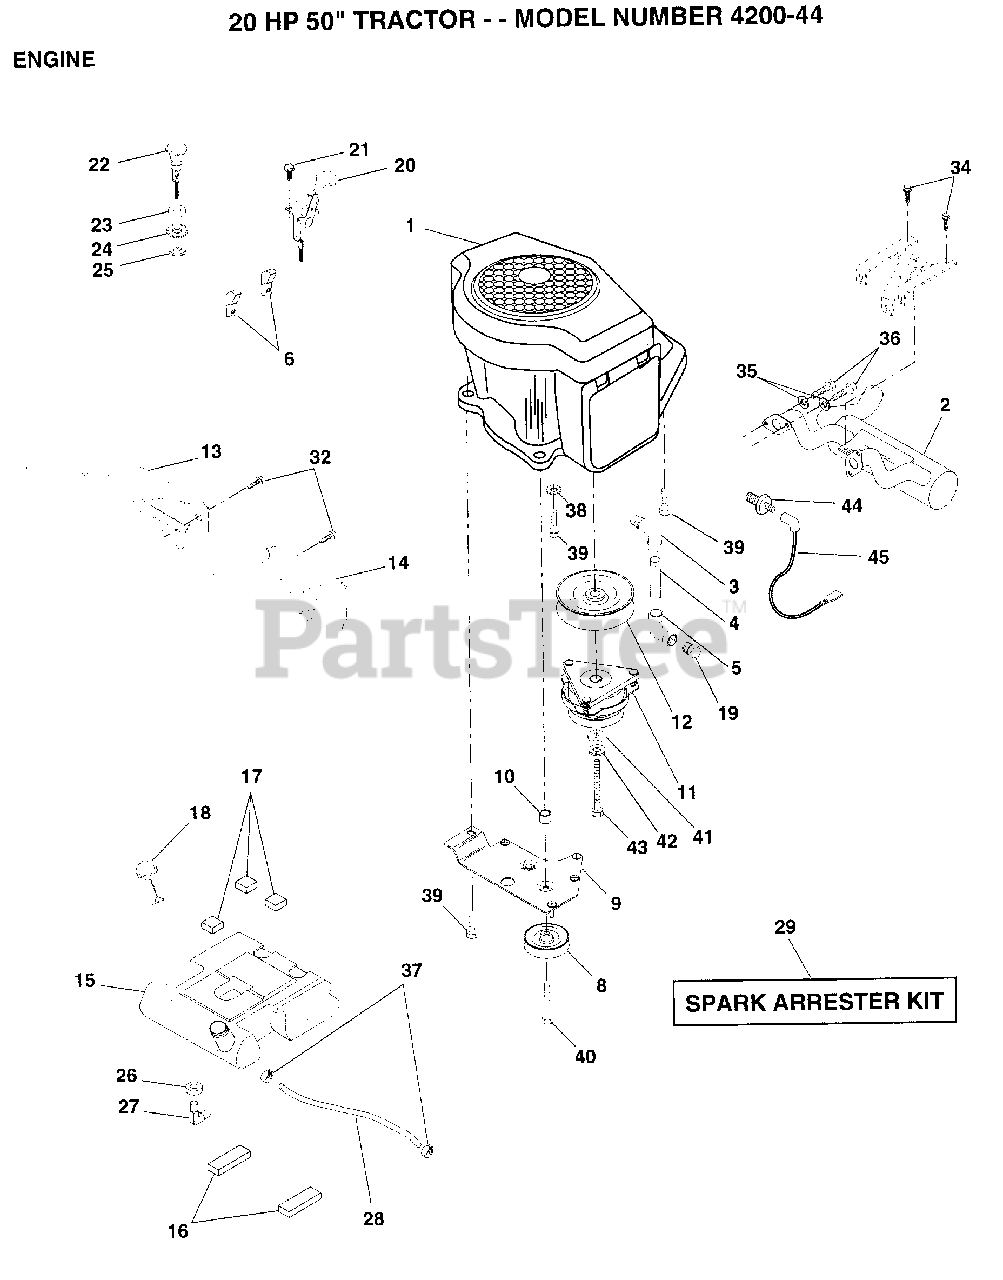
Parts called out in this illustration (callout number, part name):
1	ENGINE KOHLER MODEL
3	STREET ELBOW LT
4	PIPE NIPPLE
5	ELBOW
6	CLAMP.TUBE.DBL.EN
10	BUSHING.
12	PULLEY.ENGINE.VGT
13	BAFFLE.AIR.LH.K
16	PAD IDLER TI
17	PAD-SPACER LT
18	CAP ASM FUEL
19	PLUG T
20	CONTROL THTL 37
21	SCREW LT
22	"CONTROL.CHOKE.51"""
23	WASHER
24	LOCKWASHER
26	BUSHING OUTLET T
27	STEM.TANK.FUEL
29	SPARK ARREST KIT
32	SCREW LT
34	SCREW
35	LOCKWASHER
36	SCREW
37	HOSE CLAMP
38	LOCKWASHER
39	SCREW LT
40	SCREW.3/8-16X3.25
41	WASHER
42	LOCKWASHER
44	SWITCH OIL KOHLER
45	WIRE LEAD KOHLER
